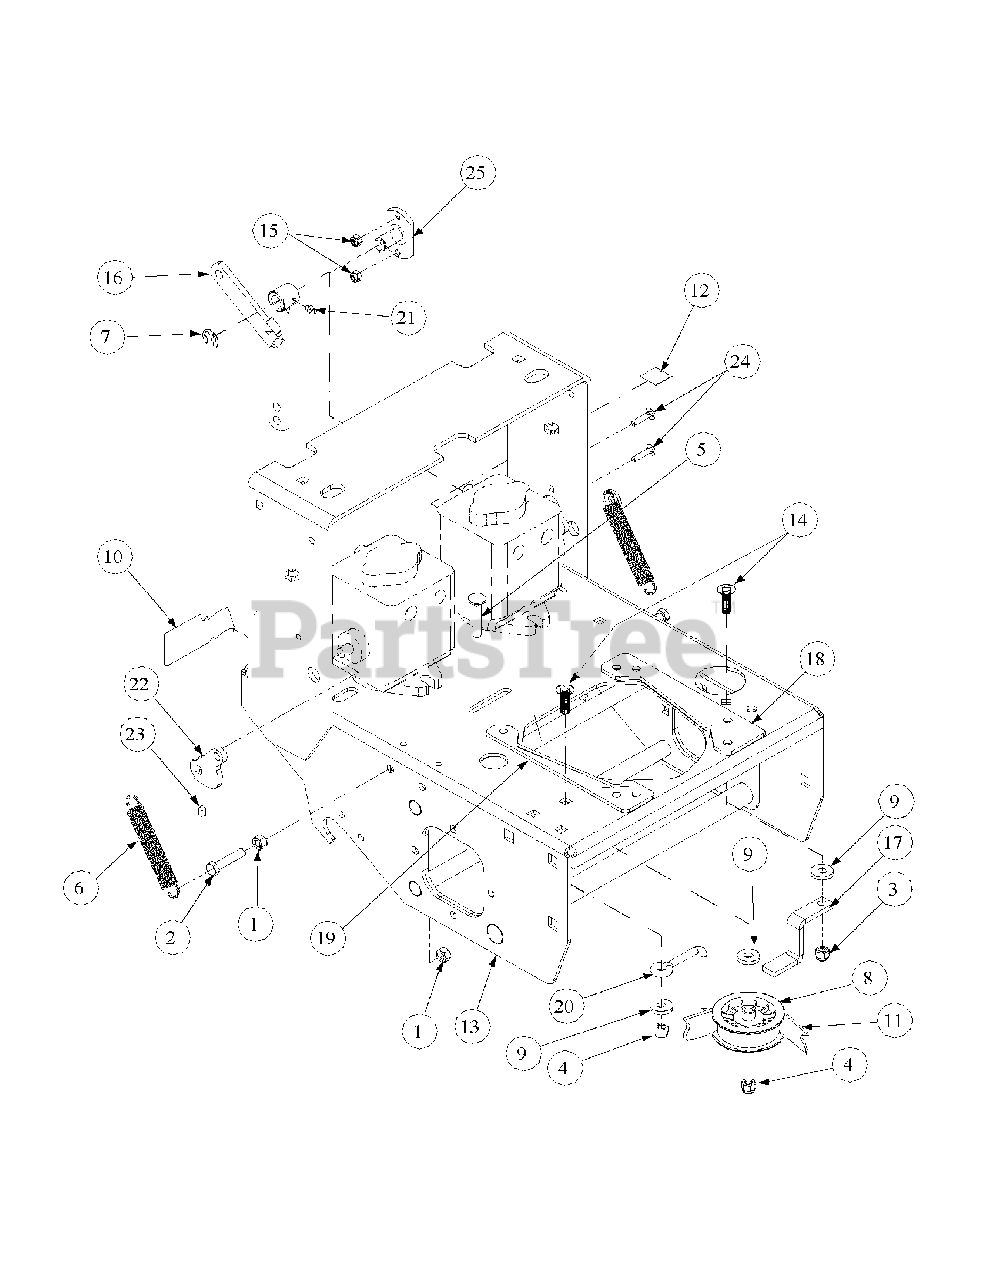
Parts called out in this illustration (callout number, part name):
1	Nut, Hex, 3/8-16 Grade C
2	Cap Screw, 3/8-16 x 1-3/4" Grade 5
3	Nut, 5/16-18, Nylock
4	Nut, L, Nylon Insert, 3/8-16 Grade A
5	Carriage Bolt, 3/8-16 x 2 Grade 5
6	Spring, Music Wire, LE-093G-9, Plated
7	E-Ring, 5/8" #5113-62
8	Pulley, Flat Idler W/Adaptor
9	Washer, Idler
10	Decal, "Made In America"
11	Belt, Hydro Pump, 36"
11	Belt, Hydro Pump, 48"
12	Label, Mower, Warn, Open Belt Drive
13	Engine Base Assembly, Hydro
14	Carriage Bolt, 3/8-16 x 1.25 Grade 5
15	Nut, L, Nylon Insert, 1/4-20 Grade A
16	Bellcrank Clutch, Casting
17	Belt Guide, Engine, 36/42/48
18	Spacer, Engine, Left Hand
19	Spacer, Engine, Right Hand
20	Belt Guide, 3.375
21	Grease Fitting, 1/4-28 x 3/16 STR
22	Pump Lever
23	Set Screw, 5/16-24 x 1.25
24	Carriage Bolt, 1/4-20 x 1.00
25	Bellcrank Pivot Weldment
